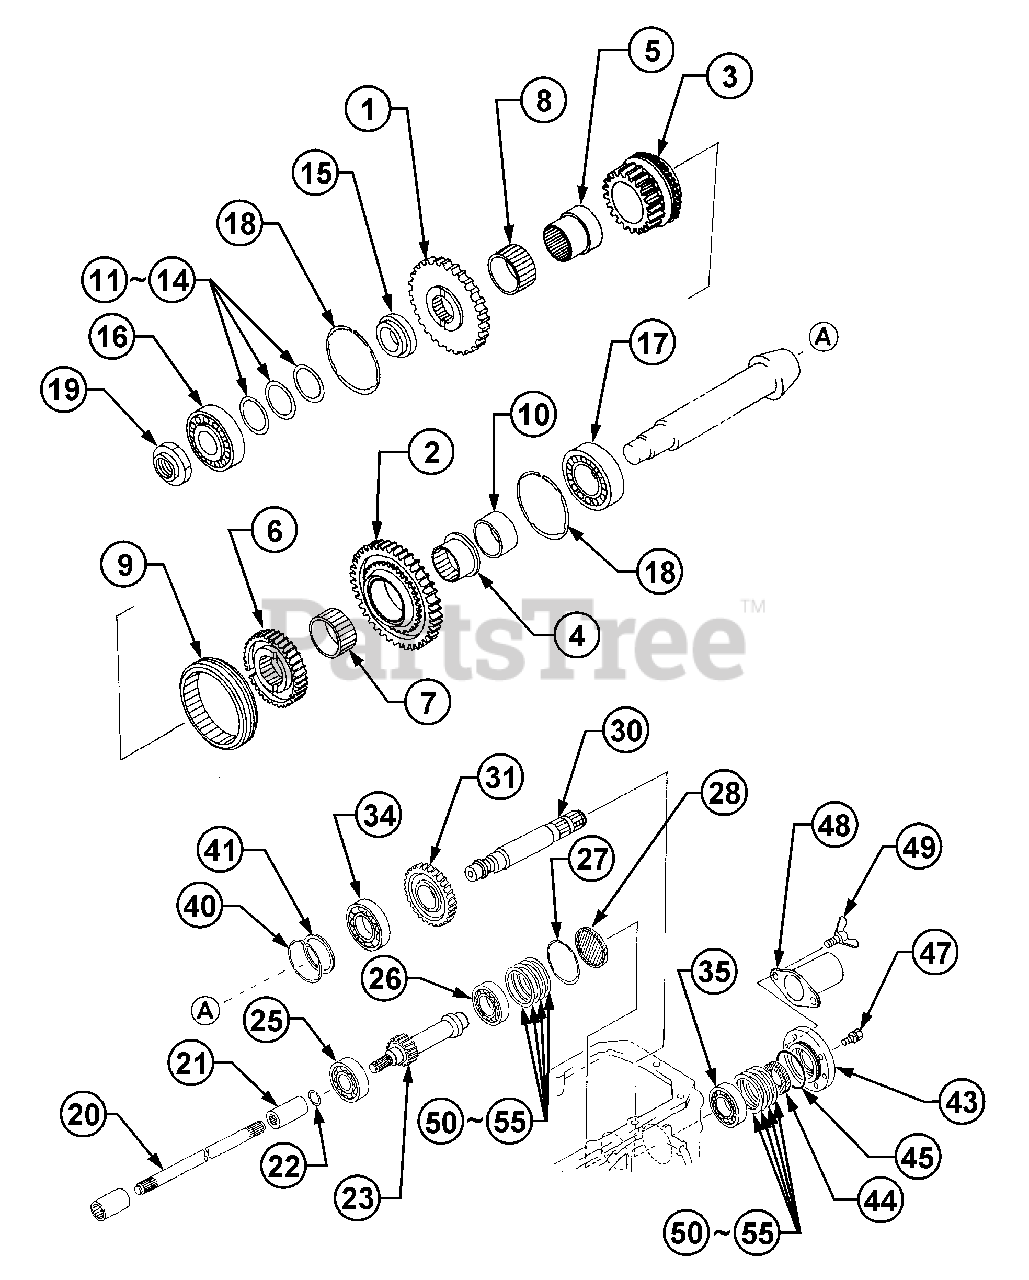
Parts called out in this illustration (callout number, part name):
7	Bearing, Needle
8	Bearing, Needle
11	Liner, t=0.15
16	Bearing, Roller
17	Bearing, Roller
25	Bearing, Ball
26	Bearing, Ball
30	Shaft, P.T.O.
34	Bearing, Ball
35	Bearing, Ball
47	Bolt, w/Washer
50	Liner, t=0.15
